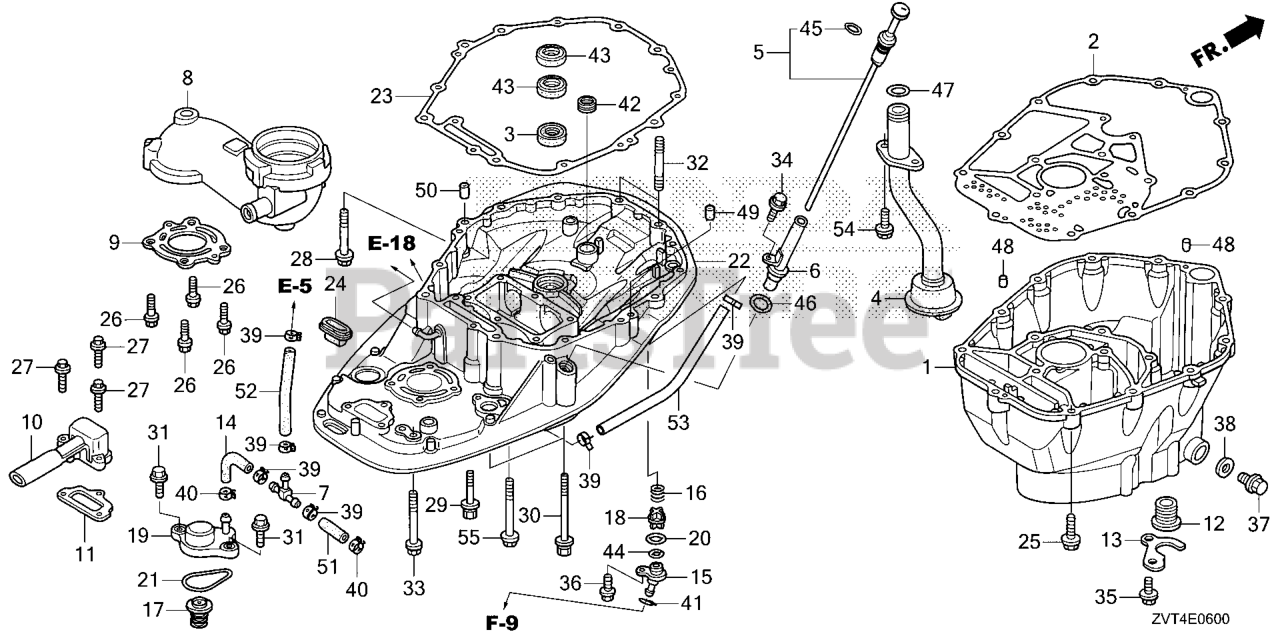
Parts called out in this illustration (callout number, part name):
1	CASE, OIL *TGRAY* (GRAY)
2	GASKET, OIL PAN
3	RUBBER, OIL PUMP
4	STRAINER, OIL
5	GAUGE COMP
6	PIPE COMP, OIL LEVEL
8	GUIDE, EX. *NH8* (DARK GRAY)
9	GASKET, EX. GUIDE
10	PORT, IDLE EX.
11	GASKET, IDLE EX. PORT
12	GROMMET, WATER TUBE
13	PLATE, WATER TUBE
14	TUBE, WATER RELIEF
15	COVER, FLUSH VALVE
16	SPRING, FLUSH VALVE
17	VALVE ASSY., RELIEF
18	VALVE, FLUSH
19	COVER, RELIEF VALVE
20	GASKET, FLUSH VALVE
21	O-RING, THERMOSTAT COVER
22	CASE COMP *NH8*
23	GASKET, MOUNT CASE
24	RUBBER, MOUNT CASE SEAL
25	BOLT, FLANGE (10X40)
26	BOLT, FLANGE (8X30)
27	BOLT, FLANGE (6X25)
28	BOLT, FLANGE (10X80)
29	BOLT-WASHER (12X70)
30	BOLT-WASHER (12X130)
31	BOLT, FLANGE (6X22)
32	BOLT, STUD (10X55)
33	BOLT, FLANGE (8X100)
34	BOLT, FLANGE (6X12)
35	BOLT, FLANGE (6X12) Use from Frame SN 1005249.
36	BOLT, FLANGE (6X20) (ENGINE NO.)
37	BOLT, DRAIN PLUG
38	WASHER, DRAIN PLUG (12MM)
39	CLAMP, TUBE (D10.5) (ENGINE NO.)
40	CLAMP, TUBE (D10.5) (ENGINE NO.)
41	CLIP B1, TUBE
42	BEARING, NEEDLE (20X28X13) (SOLID)
43	SEAL, WATER (22X35X7)
44	O-RING (16MM)
45	O-RING (8.8X1.9)
46	O-RING (15.5X3.5)
47	O-RING (20.6X2.6)
48	PIN A, DOWEL (6X10)
49	PIN A, DOWEL (10X16)
50	PIN A, DOWEL (14X20)
51	BULK HOSE, VACUUM (7X3000) (7X550)
52	BULK HOSE, VACUUM (7X3000) (7X550)
53	BULK HOSE, VACUUM (7X3000) (7X550)
54	BOLT, FLANGE (6X18)
55	BOLT, FLANGE (10X110)
